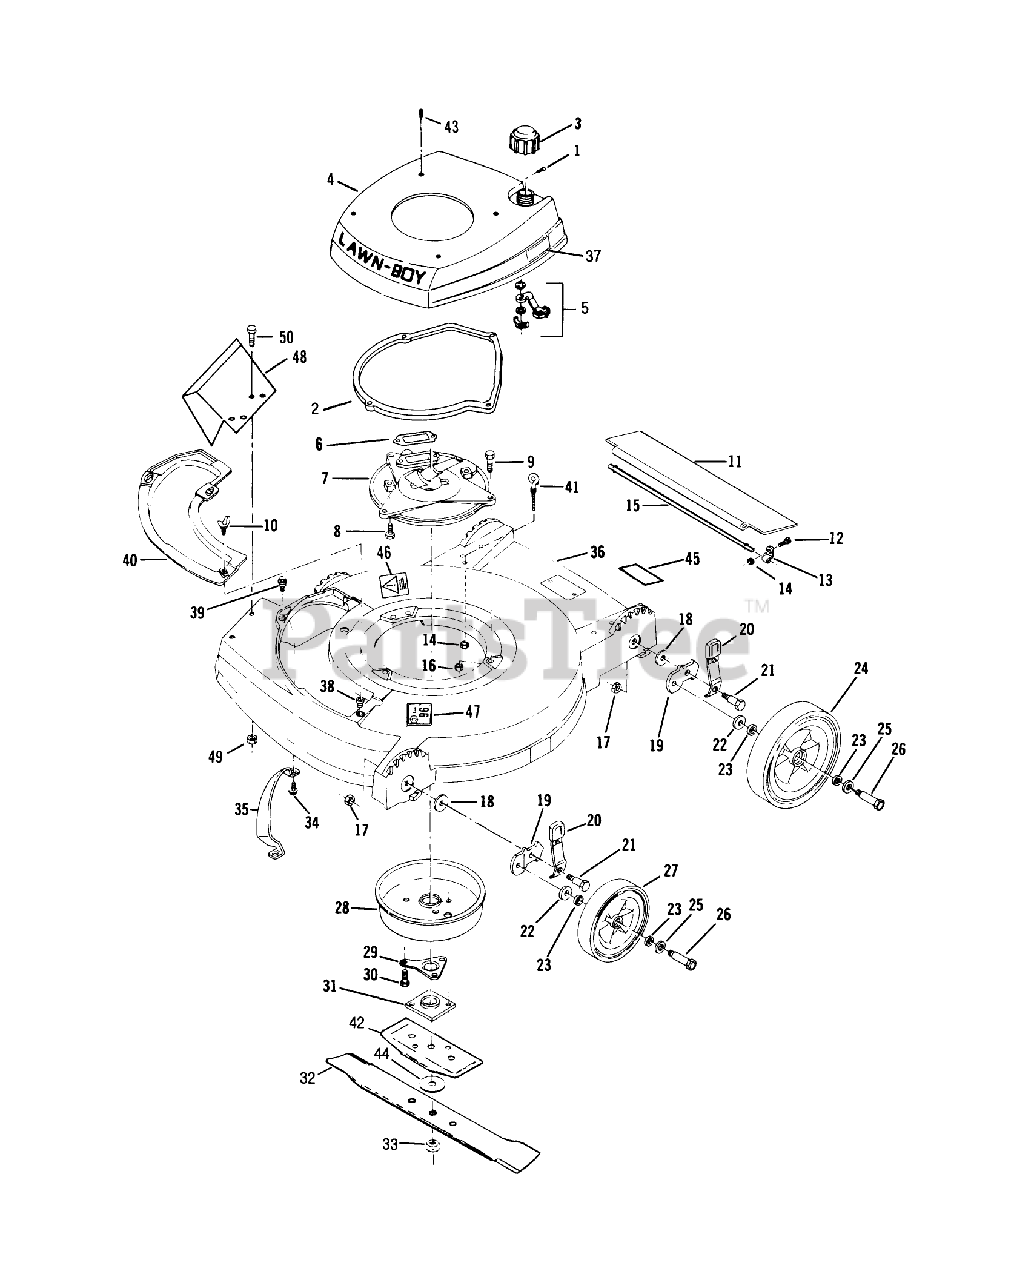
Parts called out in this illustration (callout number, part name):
1	SCREW S
3	FUEL CAP & INSERT
7	PLATE F
8	SCREW V
9	SCREW-HH
10	WING SCREW LAWRE
14	LOCKNUT E
15	ROD T/SHIELD ADV WIRE
